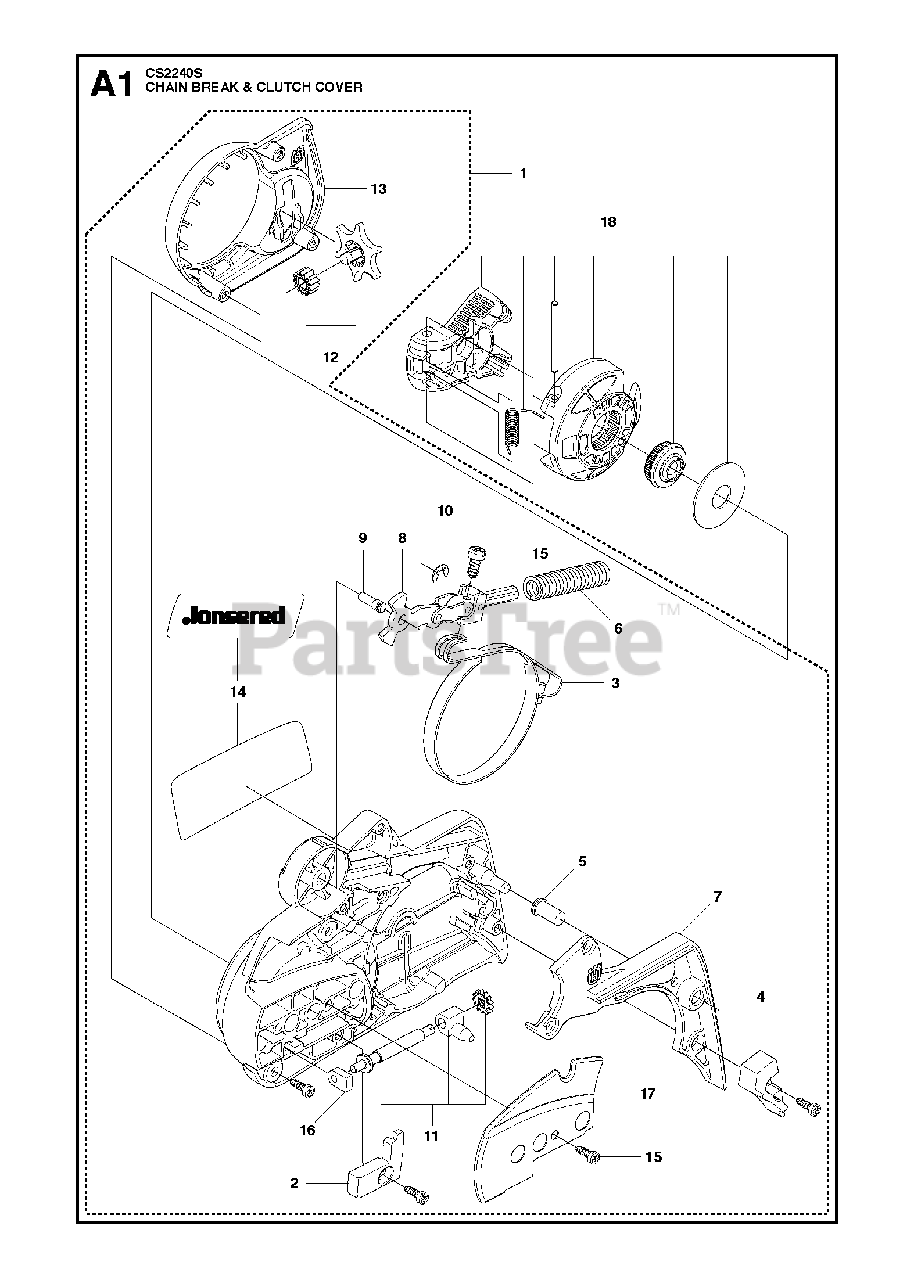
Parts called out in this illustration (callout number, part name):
1	CLUTCH COVER ASSY
2	COVER
3	BRAKE BAND ASSY
4	WEAR PROTECTION
5	SLEEVE
6	BRAKE SPRING
7	COVER
8	JOINT
9	PIN
10	E-RING 4
11	CHAIN TENSIONER SCREW, COMP.
12	CHAIN TENSIONER WHEEL
14	LABEL
15	SCREW
16	BEARING SLEEVE
17	WEAR PLATE
